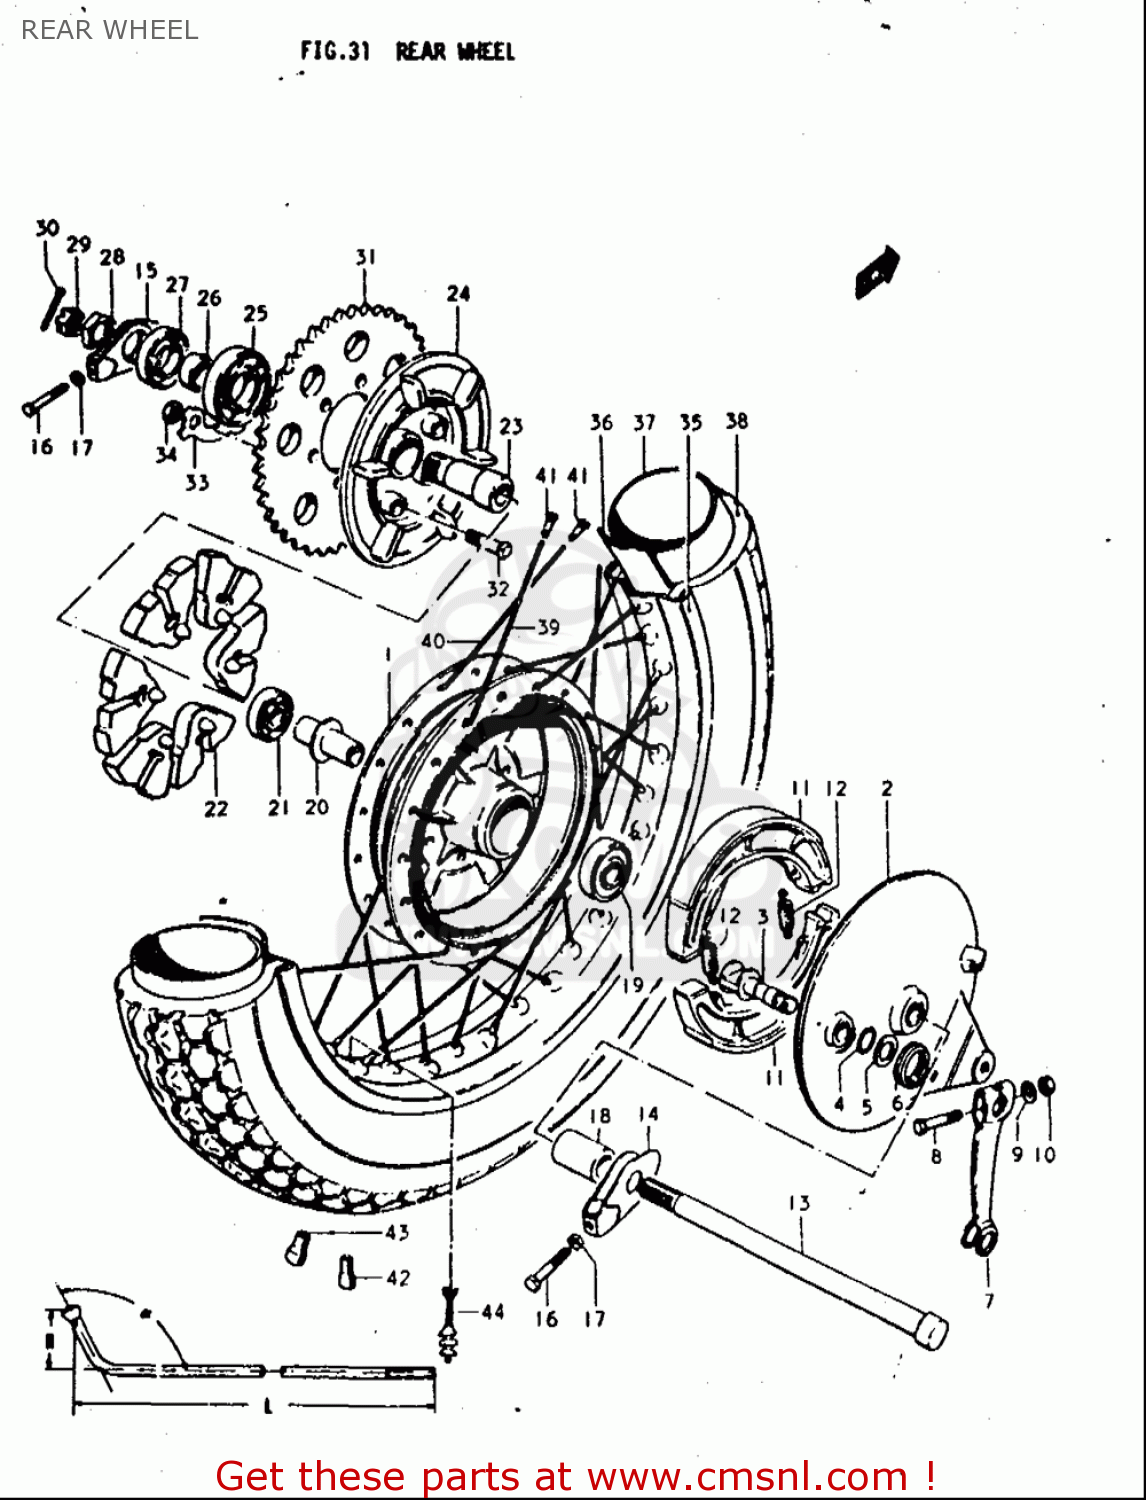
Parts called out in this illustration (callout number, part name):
3	CAM,RR BRAKE
4	O RING(D:2.4,ID:14.8)
5	WASHER(15.5X24X1.6)
6	SPRING
9	WASHER
10	NUT
11	SHOE SET,BRAKE (NAS)
12	SPRING,BRAKE SHOE
13	AXLE,REAR
15	ADJUSTER,CHAIN,L
16	BOLT(8X50)
17	NUT
19	BEARING
20	SPACER
21	BEARING
22	ABSORBER,RR HUB SHOCK
25	BEARING(25X52X15)
26	SPACER (25X30.5X11.3)
27	SEAL,OIL(30.5X52X8)
28	NUT
32	BOLT(10X35.5)
33	WASHER
34	NUT
35	RIM,RR WHEEL
36	PROTECTOR,INNER TUBE
37	TUBE ASSY,INNER
38	SPOKE SET,RR WHEEL
42	BALANCER,WHEEL (B)
43	BALANCER,WHEEL (30G)
